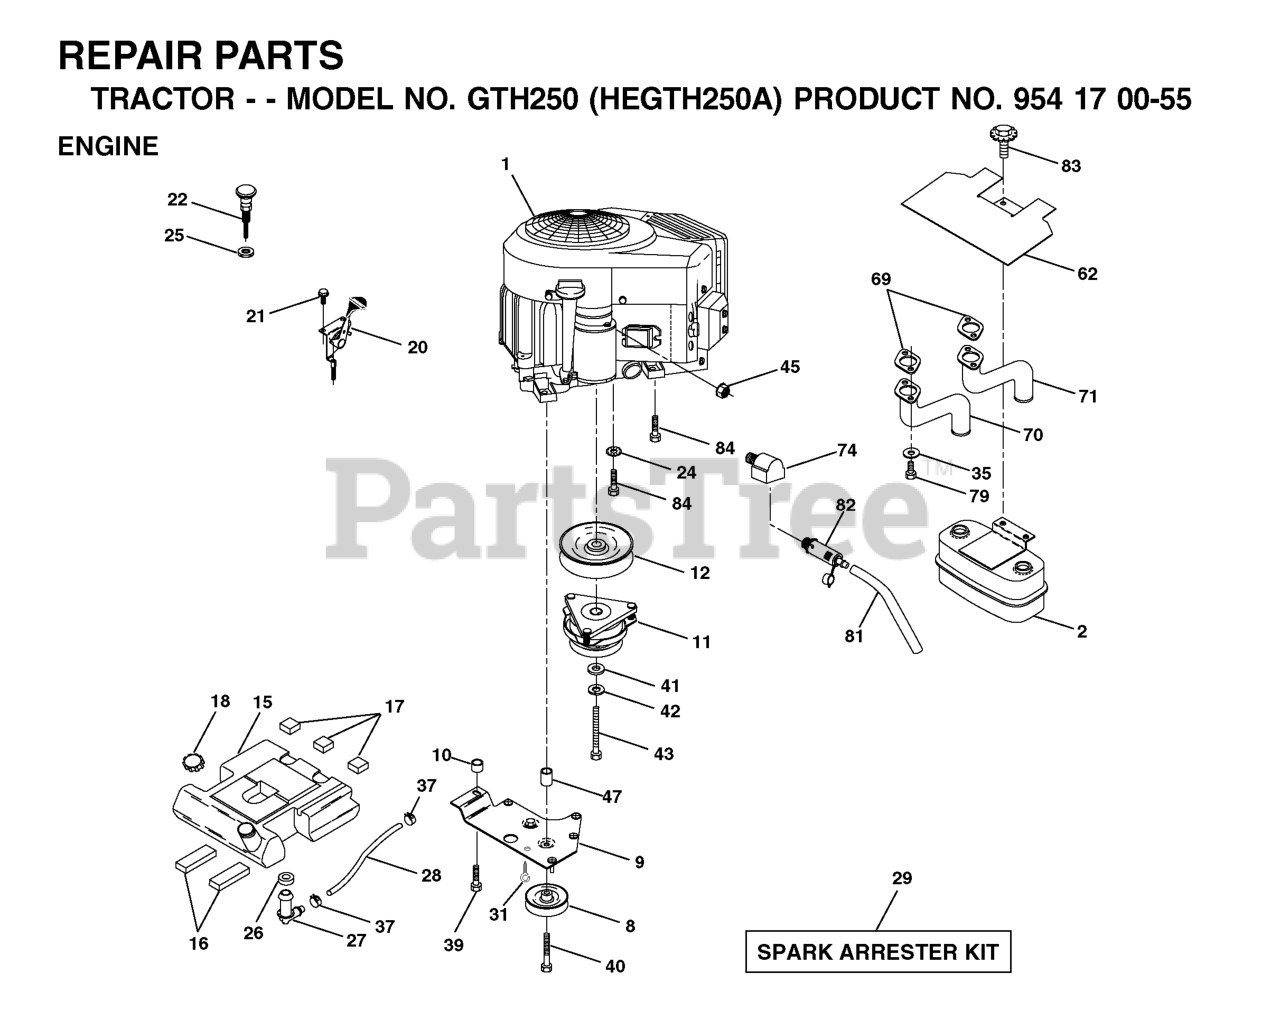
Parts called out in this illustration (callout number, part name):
2	MUFFLER.TWIN.CYL.LOW.TONE
8	RP.IDLER GROOVED
9	KEEPER ASM BELT ENGINE
11	CLUTCH
12	PULLEY ENG VGT ELECT CLUTCH
15	TANK.FUEL.5.0 LEFT.FILL.YTGT
16	PAD IDLER TI
17	PAD-SPACER LT
18	TANK CAP
20	THROTTLE CABLE
21	SCREW
22	REPL BY 532 1754-40
24	LOCKWASHER
25	Nut Keps 3/8 - 24 UNF
26	BUSHING OUTLET T
27	STEM FUEL TANK
28	FUEL LINE
29	KIT.SPARK ARRESTOR 794945 B&S
35	WASHER.LOCK.HVY.HLCL.SPR.5/16
37	HOSE CLAMP
39	SCREW TT 3/8-16X2-1/4 UNC
40	Screw TT 3/8-16 x 4 unc
42	LOCKWASHER
43	BOLT HEX 7/16-20 X 3.75 GR. 5
62	RP SHIELD HEAT MUFFLER
69	GASKET.MUFFLER
70	TUBE.EXHAUST.B&S.VGT.LH
71	TUBE.EXHAUST.B&S.VGT.RH
74	ELBOW STREET BRASS
79	SCREW
80	FLANGE NUT
81	TUBE, DRAIN OIL ASM.
82	PLUG, OIL DRAIN EASY
83	BOLT.5/16-18UNCX3/4 W/SEMS.BLK
84	SCREW 3/8-16 X 1-1/2
